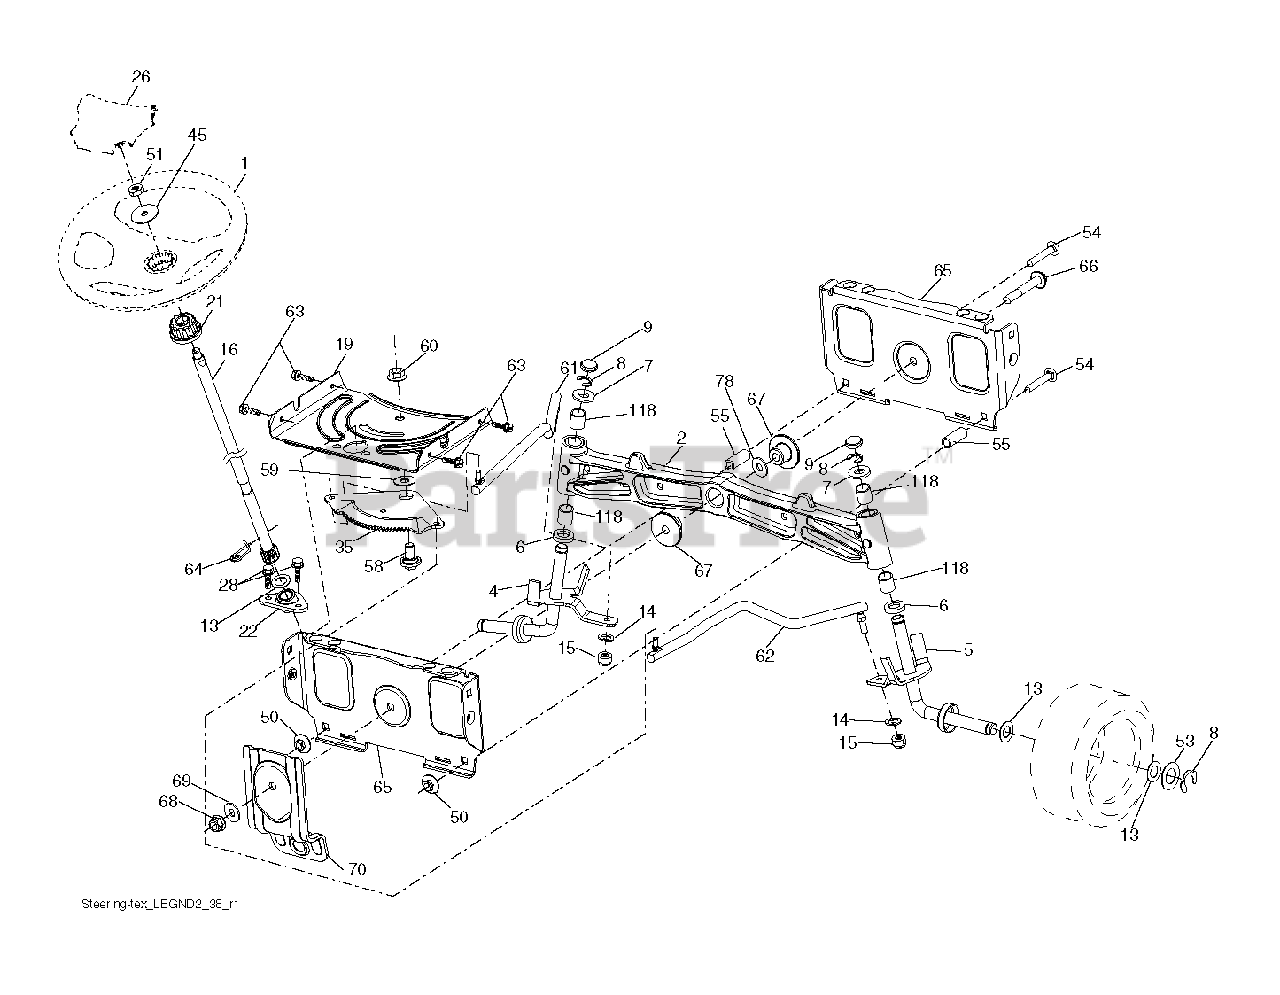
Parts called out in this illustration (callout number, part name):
1	WHEEL.STEER.HUSQ.SR.498.OVMLD
2	AXLE.SVC.ASM CAST IRON.TEX
4	SPINDLE.WELDED.LH.16"TEX
5	SPINDLE.WELDED.RH.16"TEX
6	THRUST WASHER
9	CAP.SPINDLE.BLACK
14	WASHER, LOCK 3/8
15	NUT CROWNLOCK 3/8-24
16	SHAFT.STEER.STEALTH.DD
19	PLATE.STEER.DDL.NLT/NG
21	ADAPTER, WHEEL STNG..
22	STEERING.SUPT.LOWER.
26	INSERT.CAP.WHL.STRG.HUSQ.PREM
28	SCREW, 3/8-16X3/4
35	GEAR.SECTOR.PLATE.DDL.
45	WASHER 9/16"ID, 2 3/8"OD
50	NUT LOCK FLG 3/8-16 UNC
51	NUT.HEX.1/2-20
53	WASHER.HARDENED
55	SPACER.BRACE.AXLE
58	BOLT.SHOULDER.SECTOR.P
59	WASHER.THURST.SECTOR.S
60	NUT FLANGE LOCK 5/8-11
61	DRAGLINK.LH.BALLSTUD.D
62	DRAGLINK.RH.BALLSTUD.D
63	SCREW
64	RETAINER.CLIP.SPRING.S
65	BRACE.AXLE.FRONT.NLT/N
66	BOLT HEX FGHD 7/16-14 X 3 SERR
67	BUSHING.PM.FRONT AXLE
68	NUT.LOCK.FLANGE.7/16
69	WASHER.1.5X.505X.118
70	BRKT.DECK.SUSPENSION.F
78	THRUST WASHER
118	BUSHING, AXLE CAST
